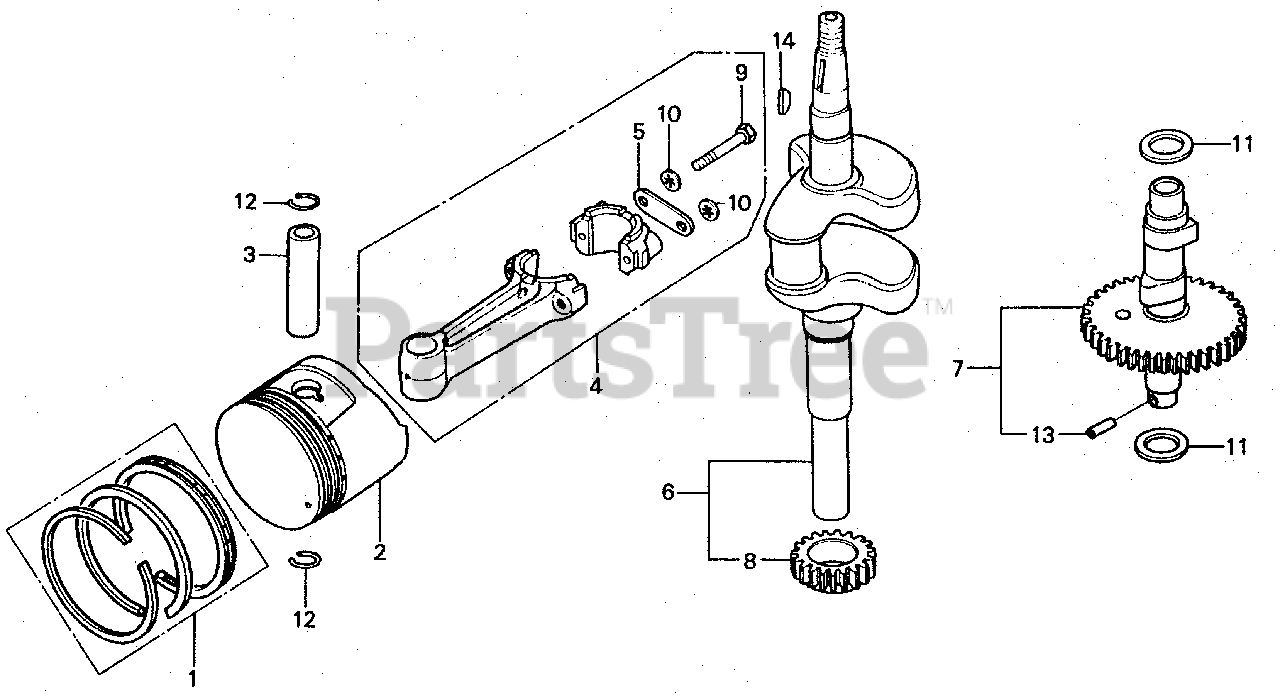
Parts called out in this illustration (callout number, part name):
1	RING SET, PISTON (STD)
1	RING SET, PISTON (OS 0.25)
1	RING SET, PISTON (OS 0.50)
1	RING SET, PISTON (0.75) (OS)
2	PISTON (STD)
2	PISTON (OS 0.25) (OS)
2	PISTON (OS 0.50) (OS)
2	PISTON (0.75) (OS)
3	PIN, PISTON
4	ROD ASSY., CONNECTING
5	WASHER, CONNECTING ROD
6	CRANKSHAFT (NOT AVAILABLE)
7	CAMSHAFT ASSY.
8	GEAR, TIMING
9	BOLT, CONNECTING ROD (7MM)
10	WASHER, LOCK (7MM)
11	WASHER, THRUST (18MM)
12	CLIP, PISTON PIN (15MM)
13	PIN, SPRING (2.5X16)
14	KEY, SPECIAL WOODRUFF (25X18)
